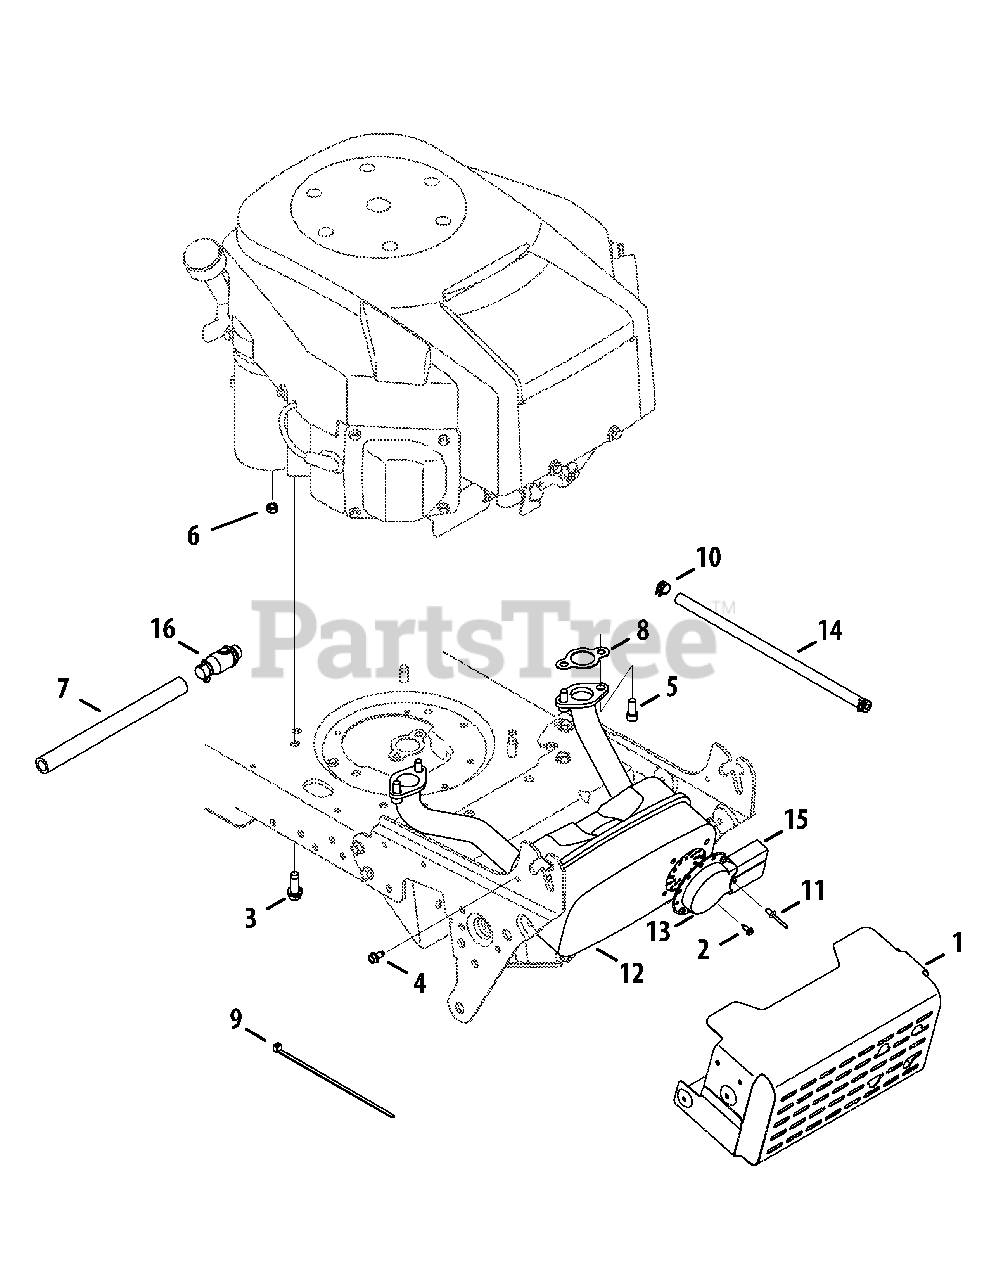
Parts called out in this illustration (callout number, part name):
1	Shield Ass’y, Muffler
3	Screw, Self-tapping, 3/8-16x1.000
4	Screw, Self-tapping, 1/4-20x0.500
5	Screw, Socket Head, 5/16-18x.750
6	Nut, Sems, 1/4-20
7	Hose, Extension, Oil Drain
8	Gasket, Exhaust, Briggs
9	Cable, Tie, 3/16 x .05 x 7.4
10	Clamp, Hose, .490 Dia.
11	Rivet, Pop, .188 Dia x .300
12	Muffler, Briggs Twin
13	Deflector, Muffler
14	Hose, Fuel, Low Permeation, 1/4
15	Deflector, Muffler, Long
16	Drain, Oil
